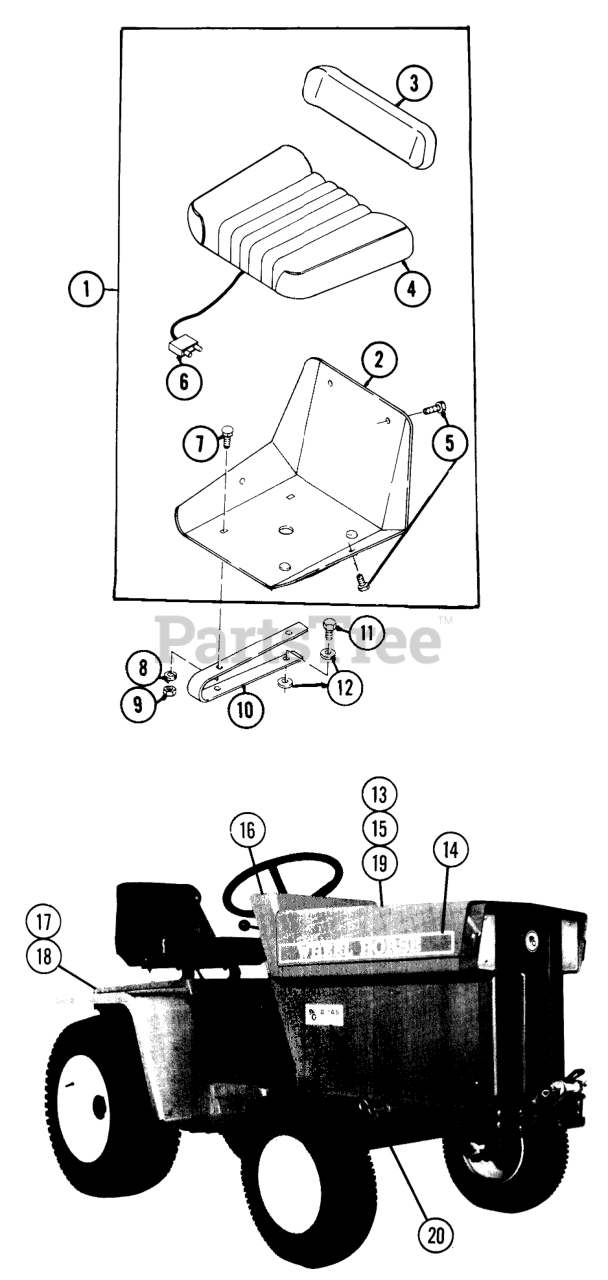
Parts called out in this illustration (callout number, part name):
2	BULLT 281
3	BULLT 281
5	Screw, Machine Indented Hex Washer Head
6	Pin Housing
13	Decal, Hood
16	Decal, Dash/Instructions
19	Decal, Caution (Battery Cover)
